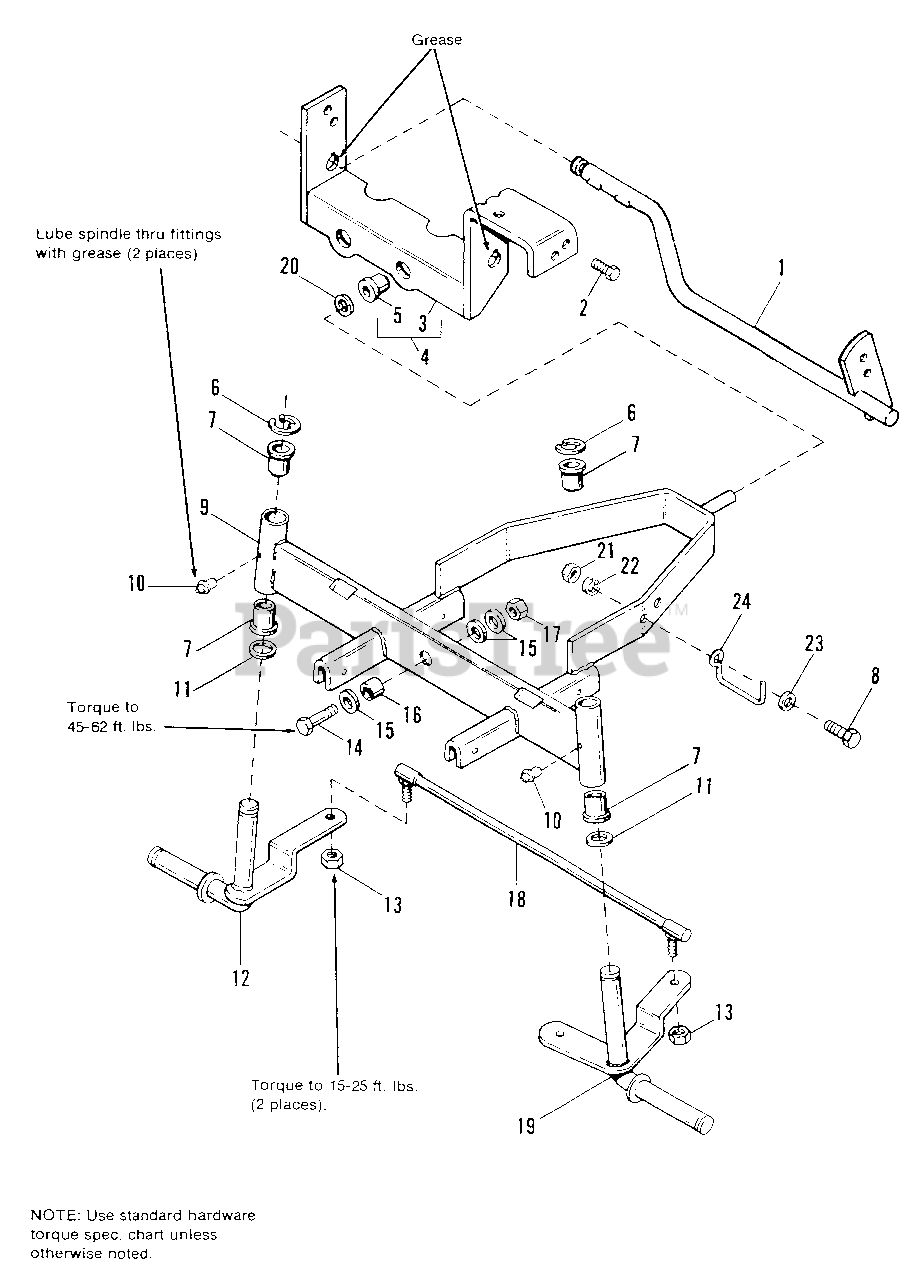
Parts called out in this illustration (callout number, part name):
1	LEVER ASSY., Brake
2	SCREW, Taptite, 5/16-18 x 3/4
4	SUPPORT ASSY., Rear (Incl. Ref. No. 3 & 5)
6	"E" RING, Ext. 3/4
8	CAPSCREW, Hex, 5/16-18 x 1
9	AXLE ASSY., Front (Incl. Ref. No. 7, 14, 16 & 17)
10	FITTING, Grease, Drive, Type
11	WASHER
12	SPINDLE ASSY., R.H.
13	LOCKNUT, Hex, 3/8-24
14	CAPSCREW, Hex, 1/2-13 x 1-3/4
15	WASHER, 9/16
16	SPACER
17	LOCKNUT, Hex, 1/2-13
18	TIE ROD ASSY.
19	SPINDLE ASSY., L.H.
20	WASHER, 5/8
21	NUT, Hex, 5/16-18
22	LOCKWASHER, 5/16
23	WASHER, 5/16
24	GUIDE, Drag Link
